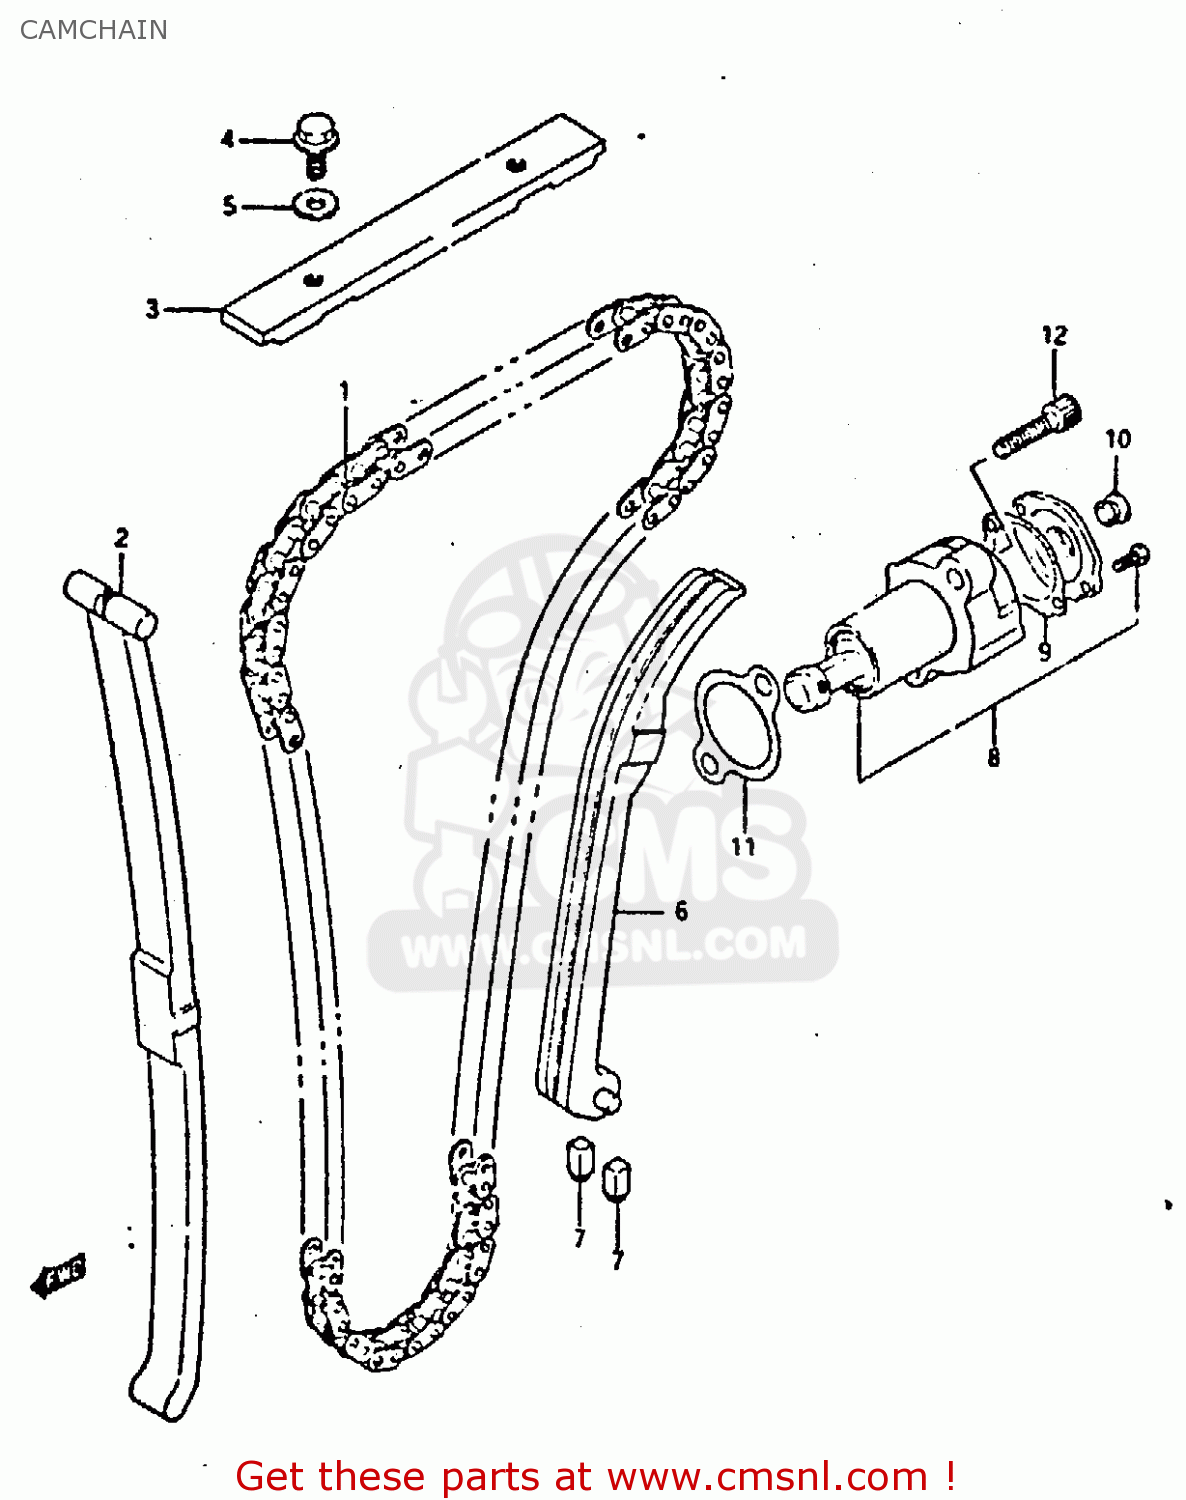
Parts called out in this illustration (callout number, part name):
1	KETTING.NOK.AS
2	GELEIDER.KETTIN
3	GUIDE,CAM CHAIN NO.2
4	BOLT
6	SPANNER.KETT.
7	CUSHION,CAM CHAIN TENSIONER
9	GASKET,ADJUSTER CAP (MCA)
10	PLUG,ADJUSTER
11	GASKET,TENSIONER ADJUSTER (NAS)
12	BOLT
